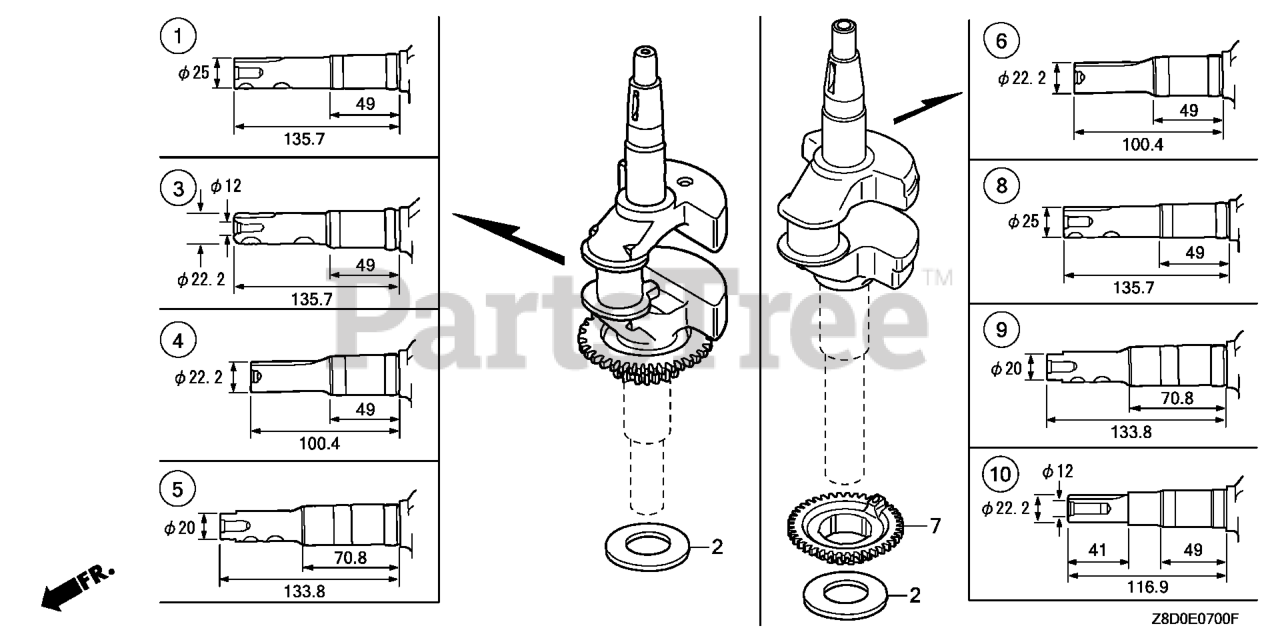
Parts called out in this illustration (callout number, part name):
2	WASHER, THRUST
6	CRANKSHAFT
7	PULLEY, TIMING BELT DRIVE
